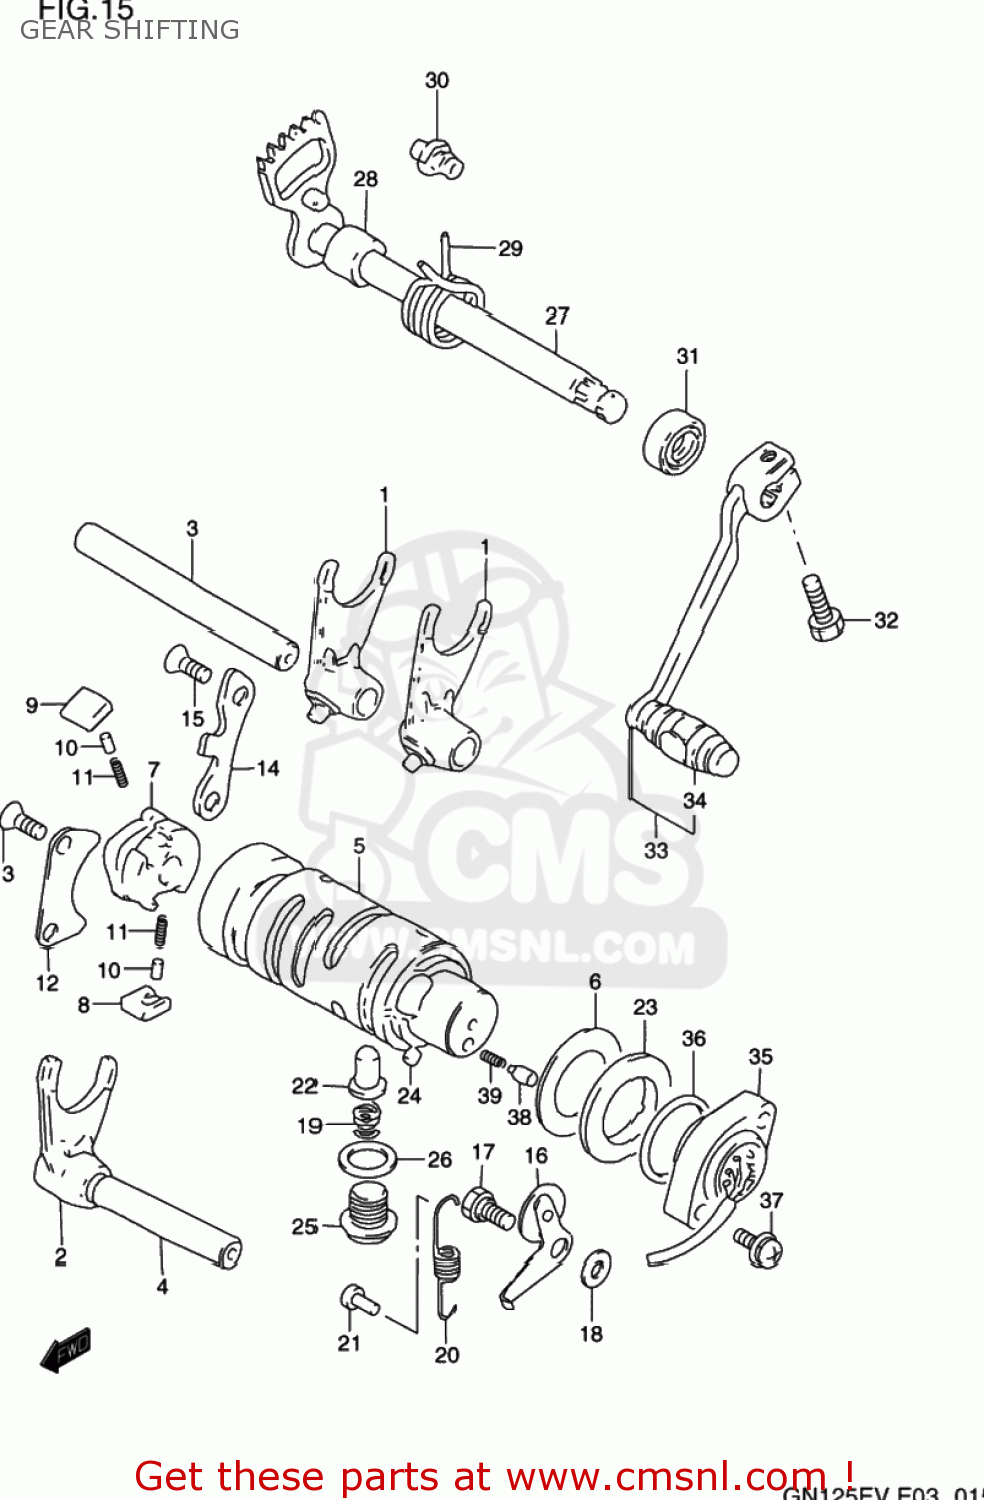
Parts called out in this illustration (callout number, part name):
1	FORK,GEAR SHIFT NO.2
2	FORK,GEAR SHIFT NO.3
3	SHAFT,GEAR SHIFT FORK
4	SHAFT,GEAR SHIFT FORK
5	CAM,GEAR SHIFT
6	WASHER,THRUST
7	GEAR,GEARSHIFT CAM DRIVE
8	PAWL,GEAR SHIFT NO.1
9	PAWL,GEAR SHIFT NO.2
10	PIN(5X8)
11	SPRING
12	LIFTER,GEAR SHIFT POLE
13	SCREW
14	GUIDE,GEAR SHIFT CAM
15	SCREW
16	STOPPER,GEAR SHIFT CAM
17	BOLT(6X14.6)
18	WASHER
19	SPRING
20	SPRING
21	RIVET
22	STOPPER,GEAR SHIFT CAM NO.2
23	PLATE,GEAR SHIFT CAM STOPPER
24	PIN
25	PLUG(14X12)
26	GASKET(13.8X18.8X4.8) (NAS)
27	SHAFT,GEAR SHIFT
28	SPACER(12X20X15.3)
29	SPRING
30	STOPPER,GEAR SHIFT CAM
31	OIL SEAL
32	BOLT
33	LEVER ASSY,GEAR SHIFT
34	RUBBER,GEAR SHIFT PEDAL
35	BASE ASSY,GEAR SHIFT TERMINAL
36	O-RING (D:2.4 ID:26.2)
37	SCREW
38	PIN(5X15.5)
39	SPRING
